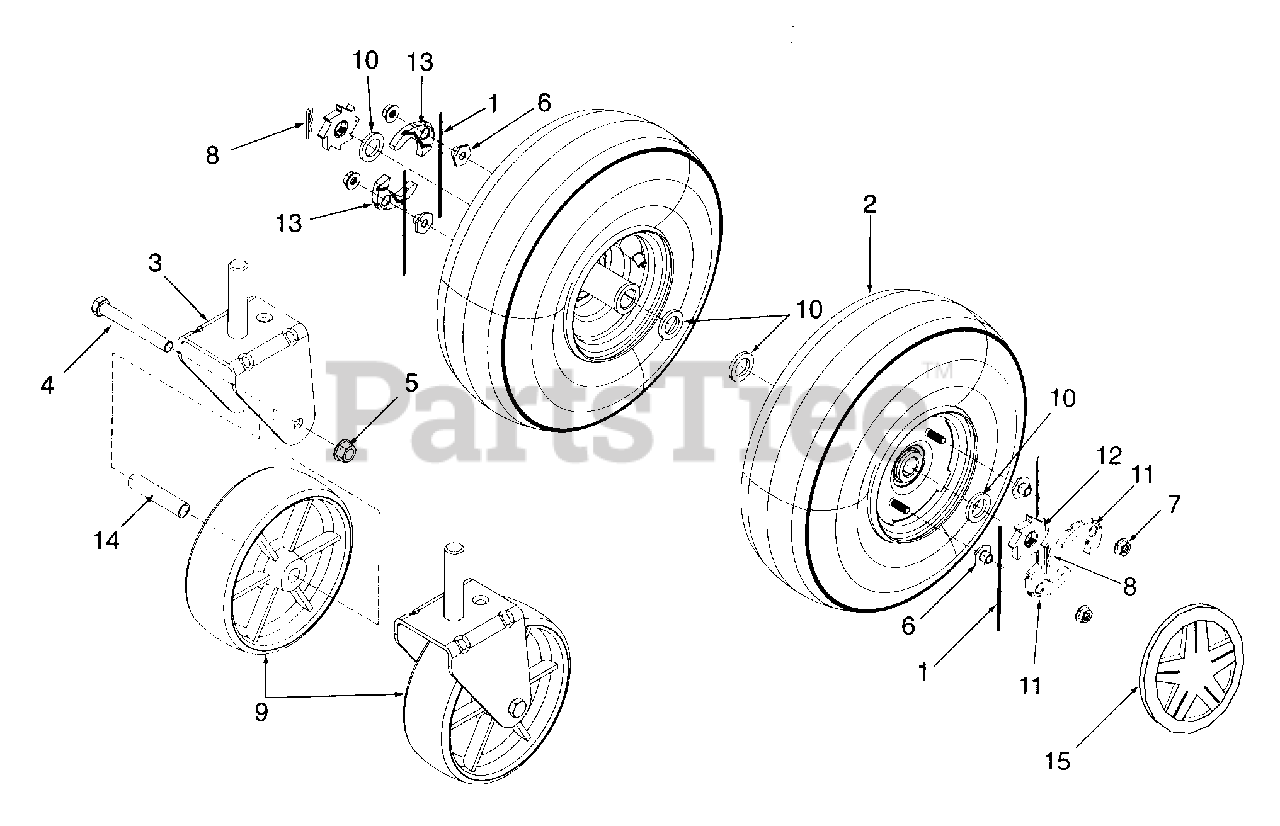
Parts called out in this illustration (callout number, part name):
1	Spring, Plastic Ratchet
3	Bracket Assembly, Pivot Wheel
4	Screw, Hex Cap, 3/8-16 x 3.0
5	Nut, Hex Flange Lock, 3/8-16
6	Nut, Special Hex 1/4-20
7	Nut, Hex Flange Lock, 1/4-20
8	Pin, Internal Cotter
9	Wheel, 6.00 x 2.00
10	Washer, Flat, .64 x 1.12 x .12
11	Pawl, LH .345 ID
12	Ratchet, Wheel, .5 Serr ID x 1.62
13	Pawl, RH .345 ID
14	Spacer, .384 ID x .5 OD x 2.3 Lg
15	Hubcap, 4.0 Beige
